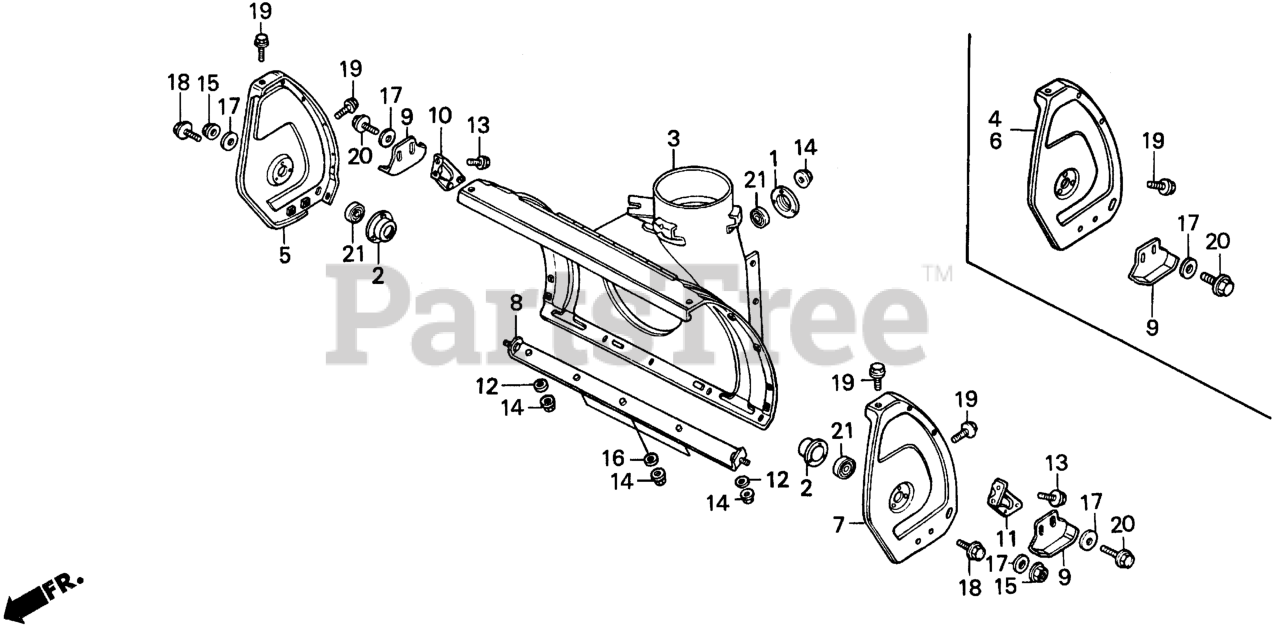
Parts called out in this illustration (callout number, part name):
1	HOLDER, L. AUGER
2	HOLDER, AUGER BEARING
3	HOUSING, AUGER (14")
4	COVER, R. AUGER SIDE (14")
6	COVER, L. AUGER SIDE (14")
8	GUARD, AUGER HOUSING
9	SKID, AUGER
12	WASHER (6X17)
14	NUT, FLANGE (6MM)
15	NUT, FLANGE (8MM)
16	WASHER, PLAIN (6MM)
17	WASHER, PLAIN (8MM)
18	BOLT, FLANGE (6X10)
19	BOLT, FLANGE (6X12) Use up to Engine SN 1543277.
20	BOLT, FLANGE (8X16) Use from Engine SN 1000016.
21	BEARING, RADIAL BALL (6203UU)
